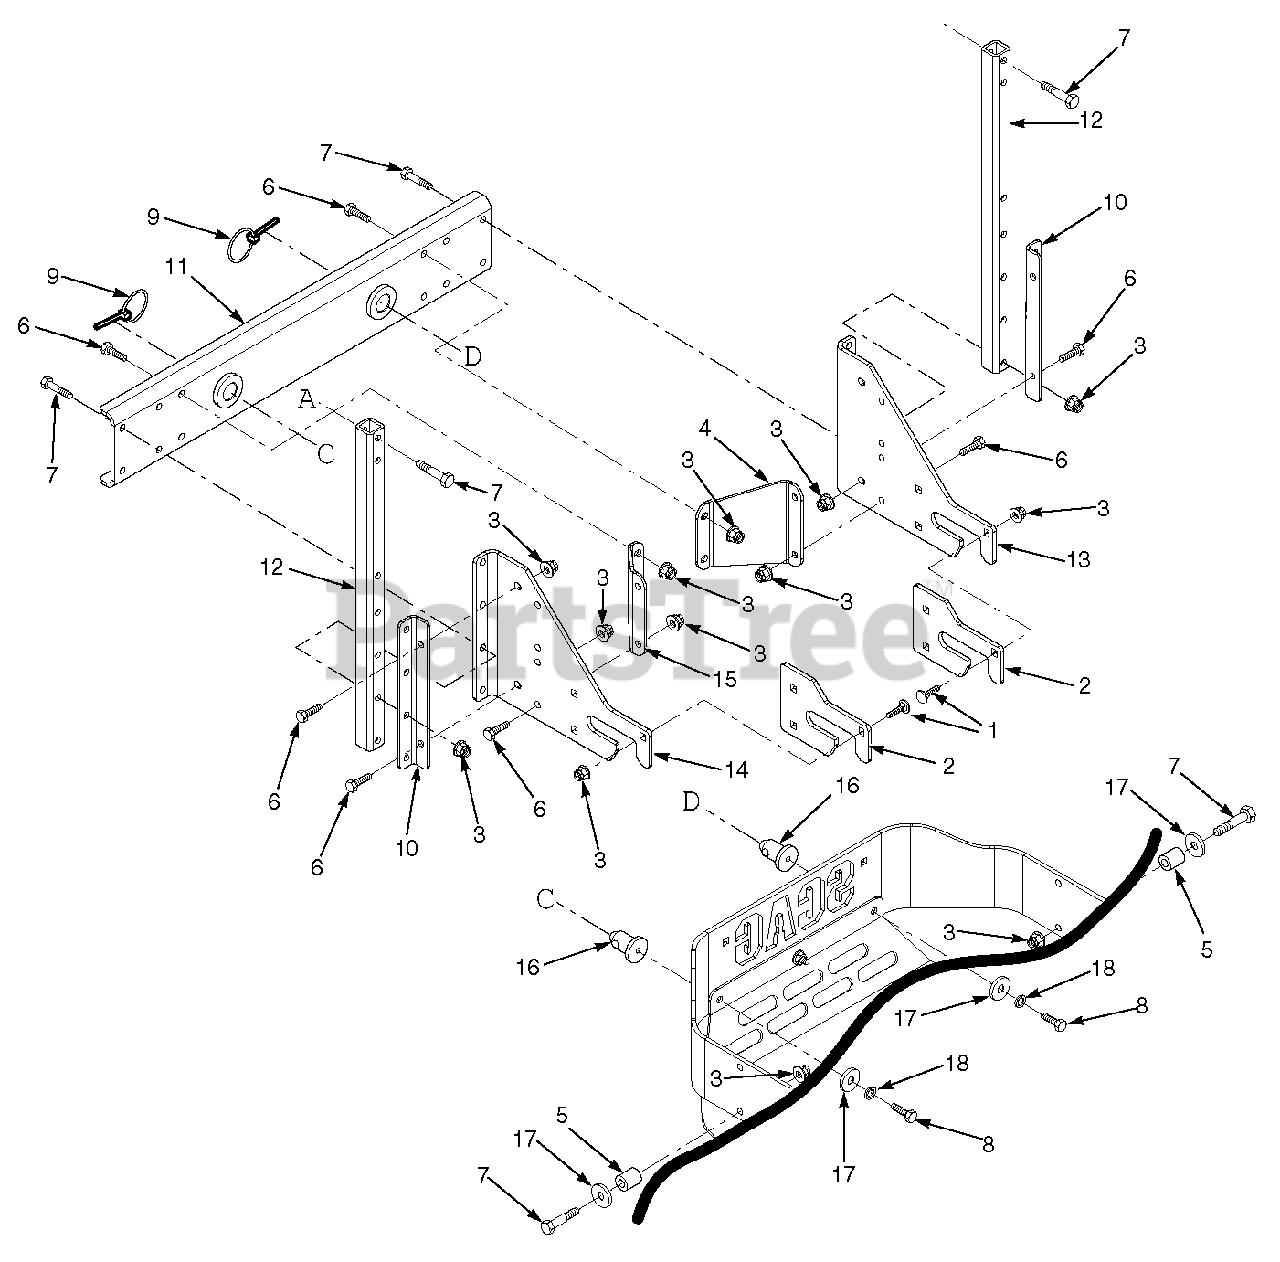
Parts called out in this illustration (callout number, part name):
1	Bolt, Carriage 3/8-16 x 1-1/4"
2	Wear Plate, GC
3	Nut, Elastic Flange 3/8-16
4	Angle Bracket, GC
5	Spacer
6	Bolt, Hex Head 38-16 x 1"
7	Bolt, Hex Head 3/8-16 x 2-1/4"
8	Bolt, Hex Head 3/8-16 x 1-1/4"
9	Quick Pin
10	Mounting Bracket, Tube
11	Mounting Bracket Weldment
12	Tube, Upright
13	Mounting Bracket, GC R.H.
14	Mounting Bracket, GC L.H.
15	Angle Bracket, GC
16	Pin, GC Locator
17	Flatwasher, 3/8-.406 x 1.50 x 7 Ga.
18	Lockwasher, 3/8"
